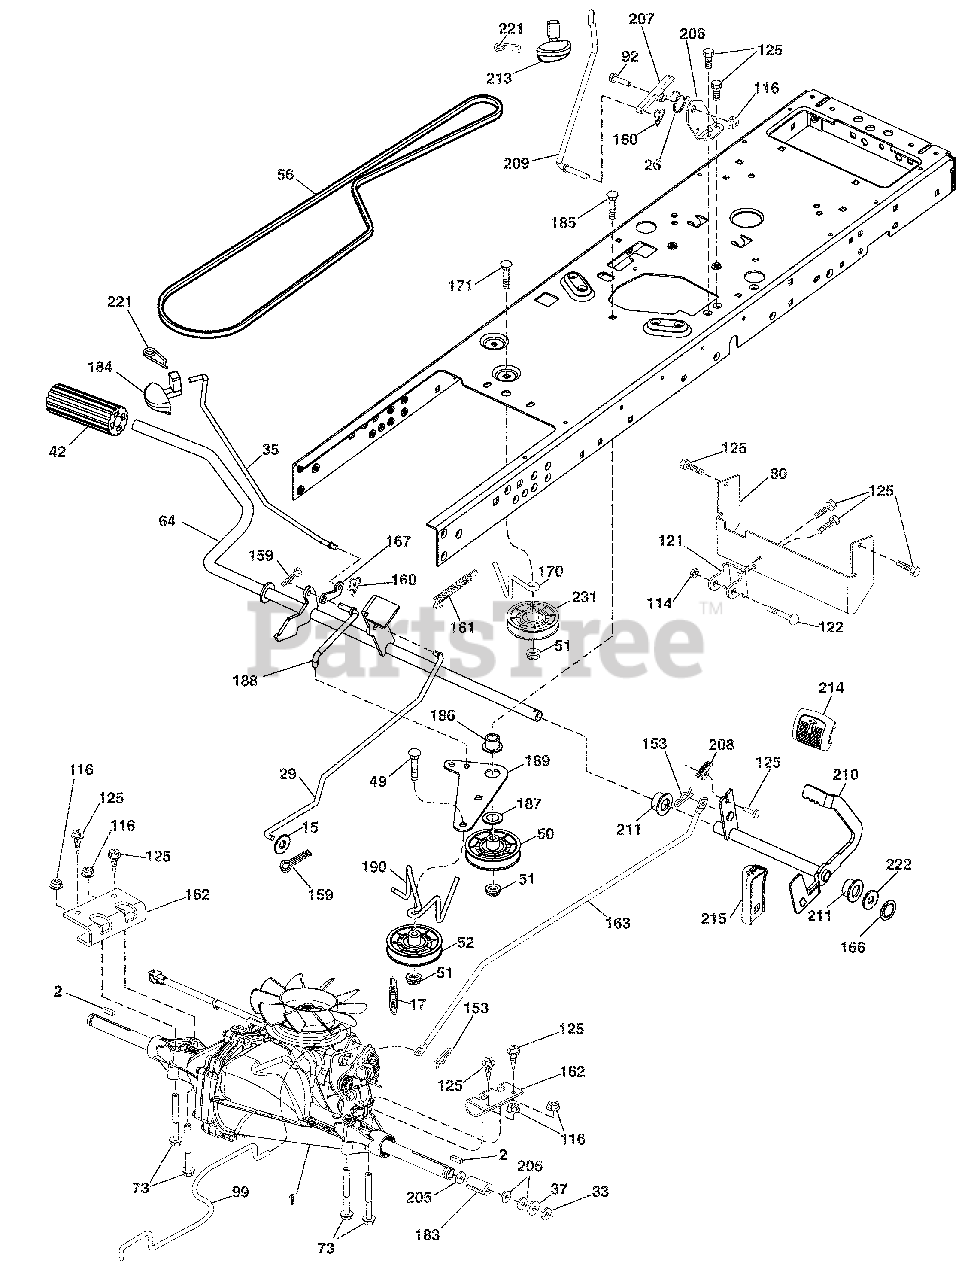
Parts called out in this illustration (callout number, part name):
2	Key Square
15	Washer 13/32 x 13/16 x 16 Ga.
17	Spring, Brake
26	Spring Return Cruise
29	Rod, Brake
35	Rod, Brake, Park
37	Washer 25/32 x 1-1/4 x 16 Ga.
42	Cover, Foot Pedal
50	Pulley Idler Flat
51	Lock Nut 3/8-16
52	Idler V-Groove 910" Offset
56	V-Belt, Drive
64	Shaft Asm. Pedal Brake Control
73	Bolt Hex 5/16-18 Gr. 5
80	Strap Torque
92	Bolt Fin Hex 5/16-18 unc x 1.25
99	Rod Spring Bypass
114	Nut Lock HX W/Ins 5/16-18
116	Nut Lock Hex Flange 5/16-18
121	Bracket Strap Torque
122	Bolt 5/16-18 x 2.50
125	Screw 5/16-18 x 3/4
153	Retainer Spring 1"
159	Pin Cotter 1/8 x 3/4
160	Retainer Clip
161	Spring, Return, Clutch
162	Adapter Transaxle
163	Rod Control
166	Nut Push
167	Latch Brake Parking
170	Keeper V-Idler
183	Spacer Axle
184	Handle Parking Brake
186	Spacer Retainer
187	Washer
188	Link Clutch Ground Drive
189	Bellcrank Ground Drive
190	Keeper Bellcrank Ground Drive
205	Washer 25/32 x 1-5/8 x 16 Ga.
206	Bracket Mount Latch Cruise
207	Latch Control Cruise
208	Gear Sector Control Cruise
209	Rod Control Cruise
210	Rocker Asm. Pedal Control
211	Bearing Nylon
213	Knob Control Cruise
214	Pedal Forward
215	Pedal Reverse
221	Retainer Spring Clip Handle
222	Washer 21/32 x 1-1/4 10 Ga.
231	Idler V-Groove 1.688" Offset
